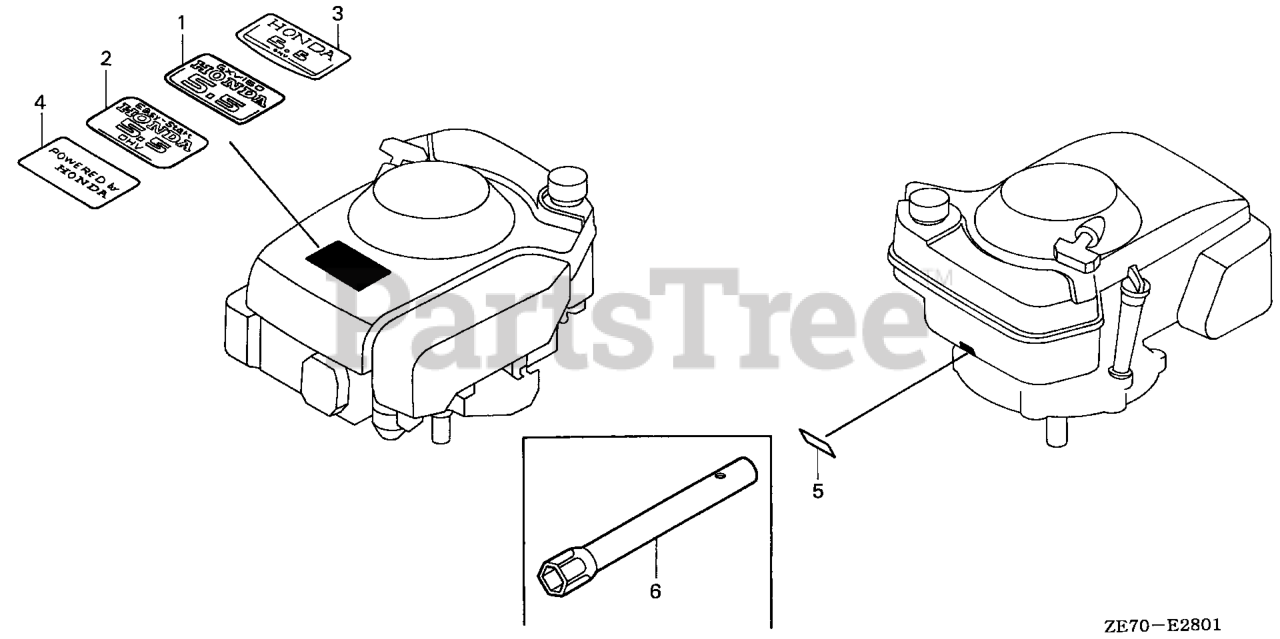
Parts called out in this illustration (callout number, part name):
2	EMBLEM (5.5)
5	MARK, TYPE (A1T)
6	WRENCH, BOX (P21)
